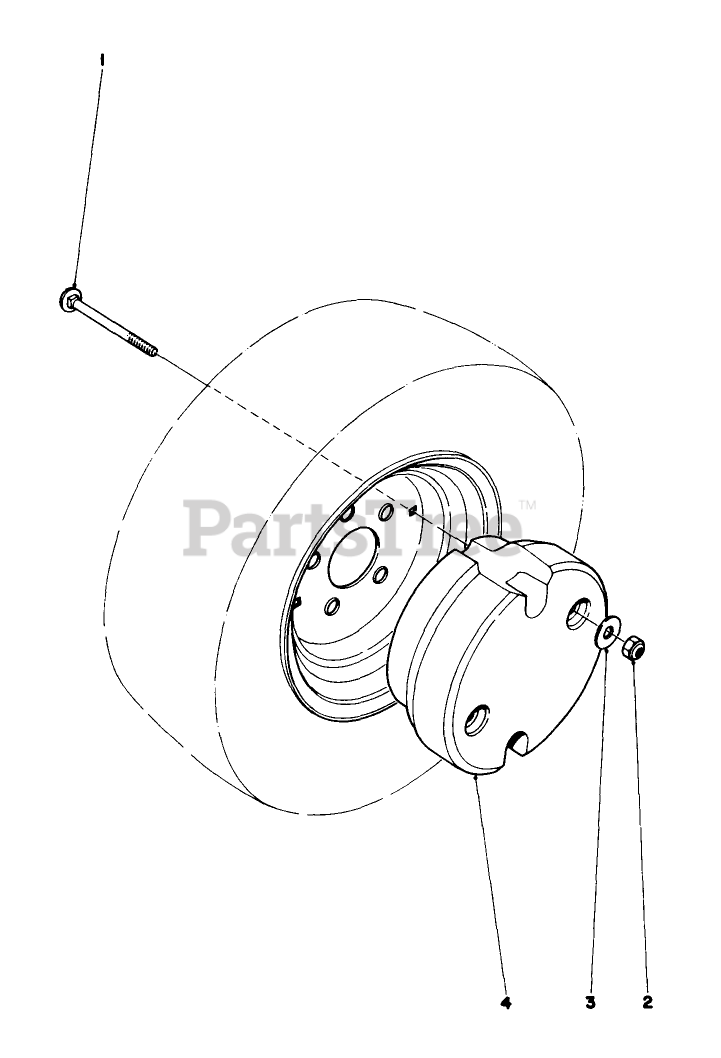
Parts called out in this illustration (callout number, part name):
1	SCREW-CARR
2	NUT-LOCK, NI
3	WASHER-FLAT
4	Wheel Weight
